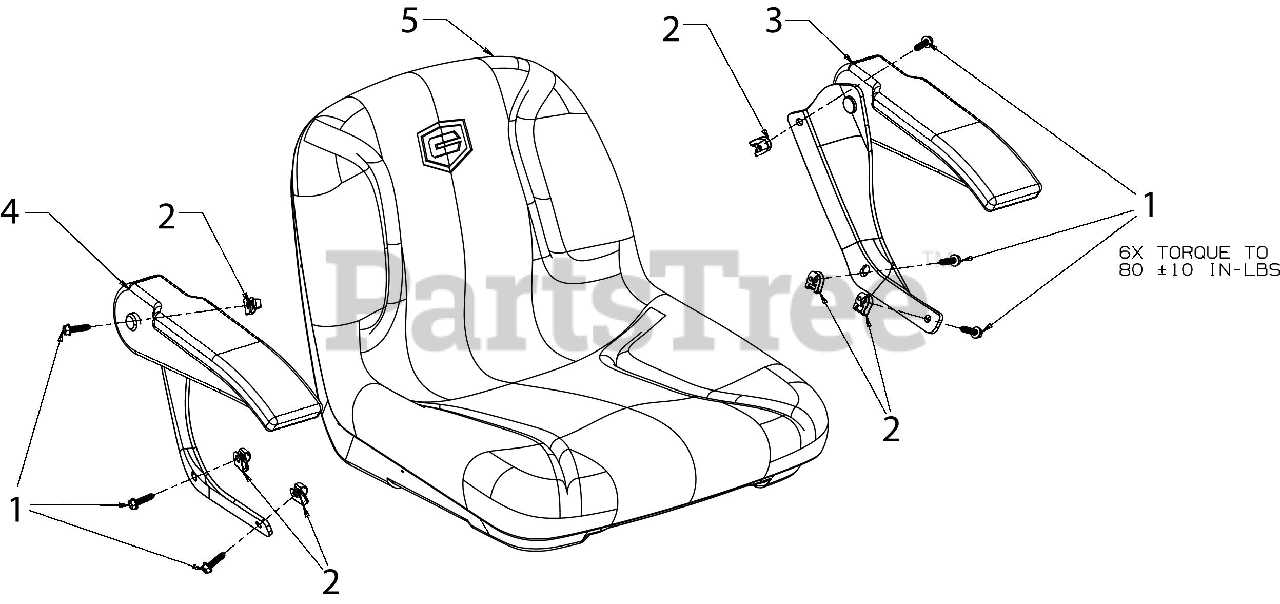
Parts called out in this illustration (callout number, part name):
1	SCREW 1/4-14X 1.00
2	ARMREST SPEED NUT
3	LH & RH ARMREST KIT
4	LH & RH ARMREST KIT
5	HIGH BACK SEAT CRAFTSMAN
